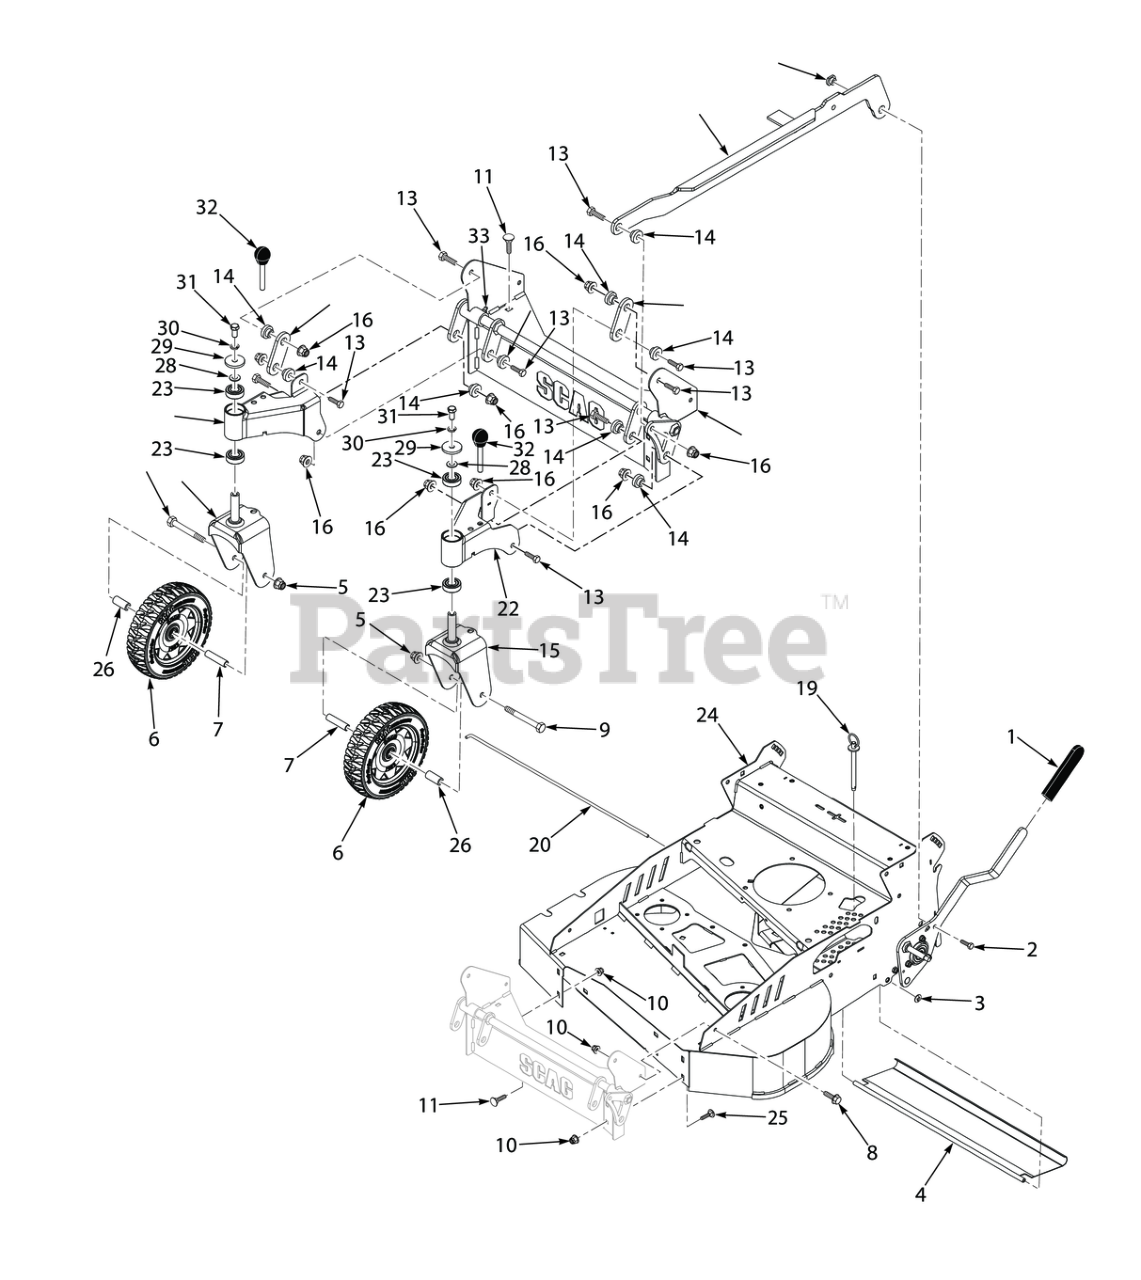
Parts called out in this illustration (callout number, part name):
1	Grip, Deck Lift
2	Bolt, Hex Head, 3/8-16 x 3/4"
3	Nut, Push-On 5/16-18
4	Trail Shield
5	Nut, Flange Elastic Stop Nut, 3/8-16
6	Wheel Assembly, Front
7	Spacer, Front Wheel
8	Cpscrw, 5/16-18 x 1"Serrated Flange Hex Head
9	Capscrew, Hex Head 3/8-16 x 2.75"
10	Nut, Flange Head Elastic Stop 5/16-18
11	Bolt, 5/16-18 x .75 RHSN Carriage
12	Caster Lift Support Weldment
13	Bolt, Hex Head 3/8-16 x 1-1/4", Kawasaki FX / FS
14	BUSHING, SPEED ADJUSTMENT LEVER
15	Yoke Weldment
16	Nut, Flange Elastic Stop Nut, 3/8-16
17	Weldment Deck Lift
18	Pivot, Deck Weldment
19	Ring Pin, 3/8 x 4"
20	Rod, Trail Shield
21	Bracket, Link
22	Yoke Support Weldment, LH
23	BEARINGS, BALL, NEUTRAL RETURN
24	Panel, Instrument w/Decal (Kohler EFI)
25	Bolt, Carriage 5/16-18x1" (large frame units only)
26	Pivot, Brake Lever
27	Yoke Support Weldment, RH
28	Flatwasher, 3/8 (.406 x .812 x .065)
29	Flatwasher, 3/8-.406 x 1-1-1/2 x 7 Gauge
30	Lockwasher, 3/8" Spring, Kawasaki FX / FS
31	Bolt, Hex Head, 3/8-16 x 3/4"
32	Pin Assembly, Swivel Lock
33	GREASE FITTING, STR. 1/4-28 SELF TAP.
